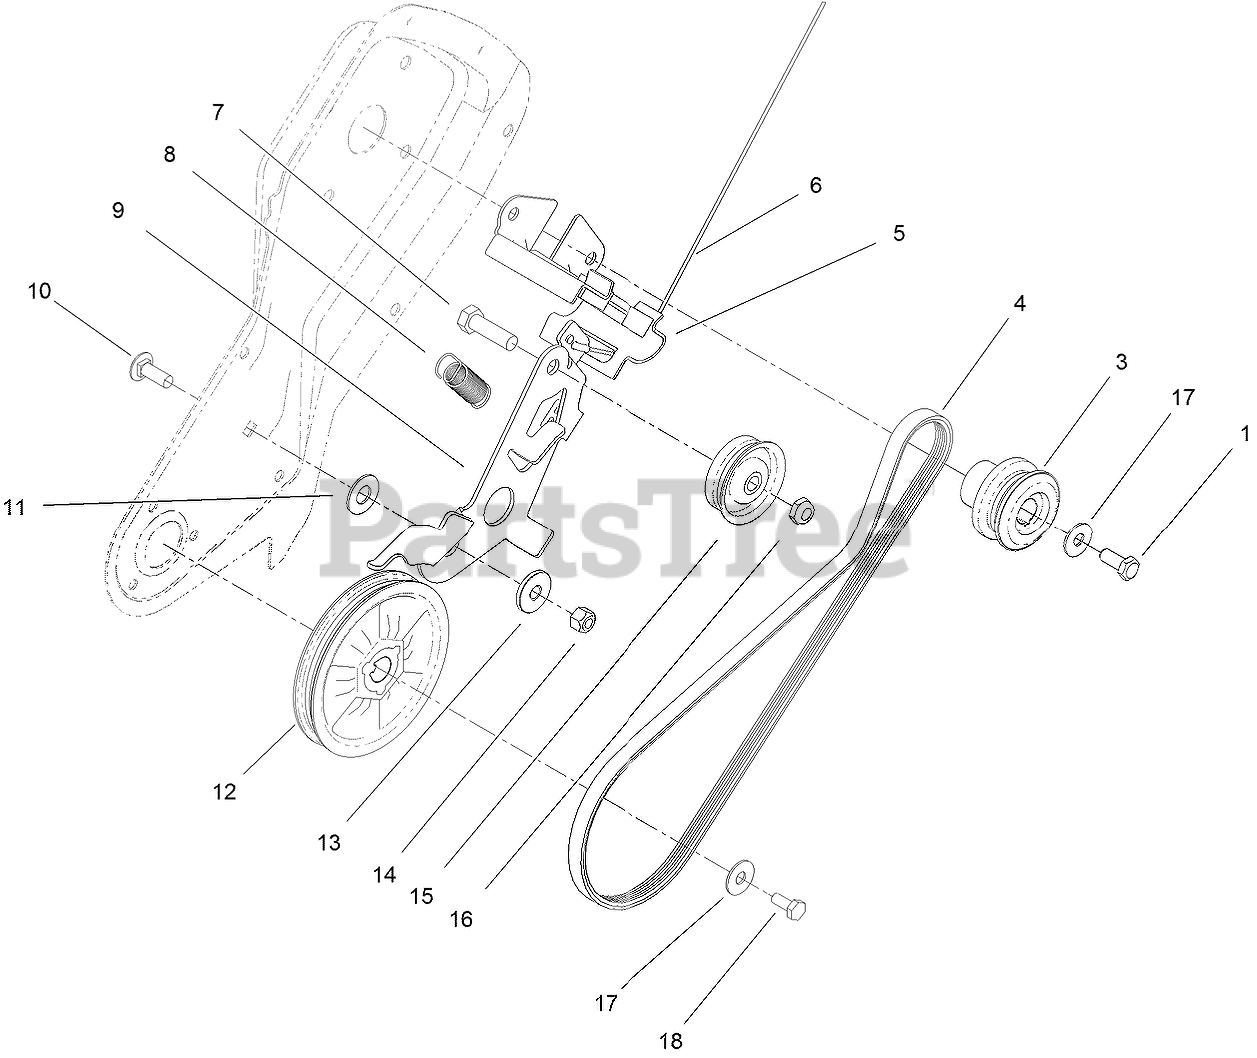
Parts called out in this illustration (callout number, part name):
1	SCREW-HH LOCK
3	PULLEY-ENGINE
4	BELT-V, RIBBED
5	GUIDE-BELT
6	CABLE-CLUTCH
7	SCREW-HH
8	SPRING-BRAKE
9	ARM-IDLER
10	BOLT-CARR
11	WASHER
12	ROTOR PULLEY ASM
13	BUSHING-IDLER
14	NUT-HEX
15	PULLEY-IDLER
16	NUT-HEX
17	WASHER-BELLEVILLE
18	SCREW-HH LOCK
